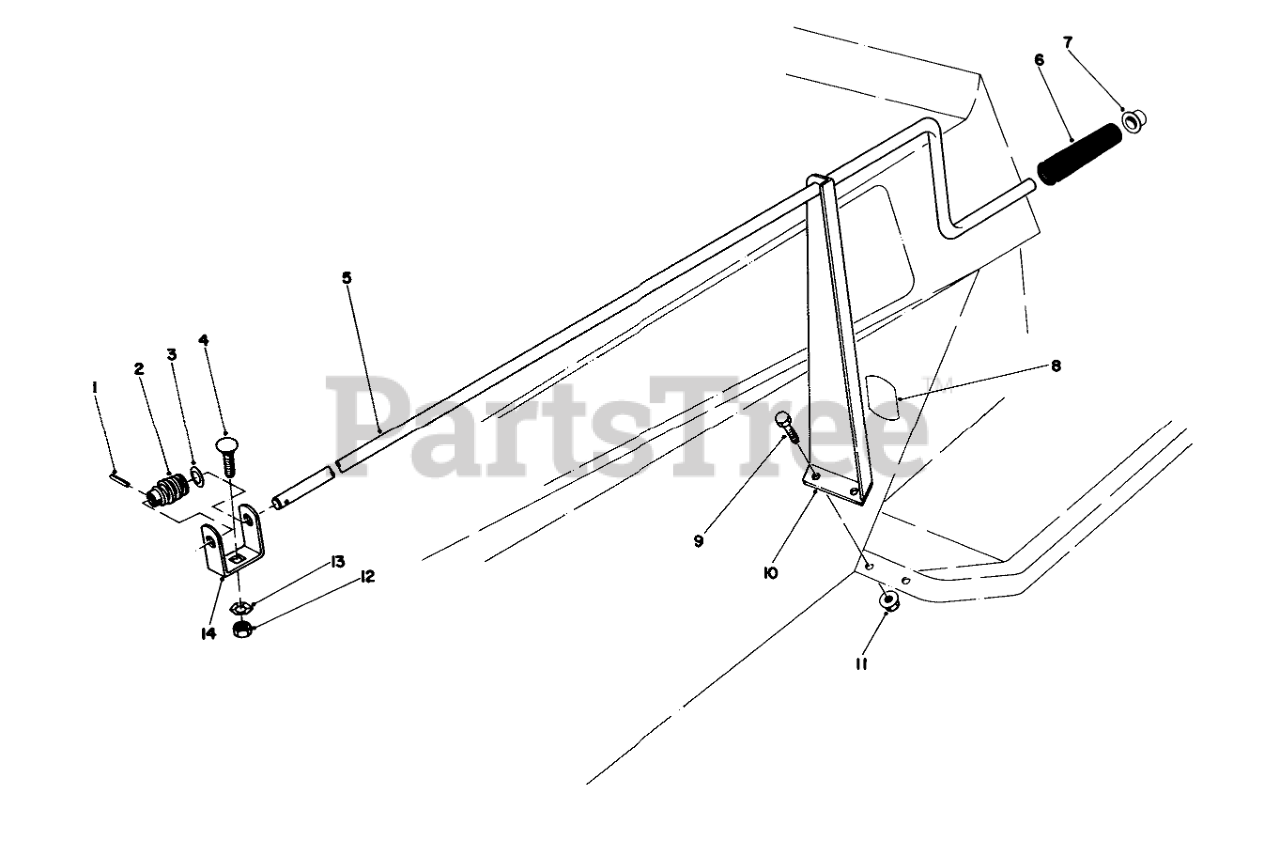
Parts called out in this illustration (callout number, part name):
1	PIN-SPRING
2	GEAR-WORM, CHUTE
3	WASHER-SPRING
4	BOLT-CARR
5	ROD-CHUTE CONTROL
6	GRIP-CONTROL, CHUTE
7	RETAINER-PUSH ON
8	CHUTE DECAL
9	SCREW-HH
10	CHUTE CONT BRKT B
11	NUT-HF
12	NUT-LOCK, NI
13	WASHER-LOCK
14	WORM BRKT B
